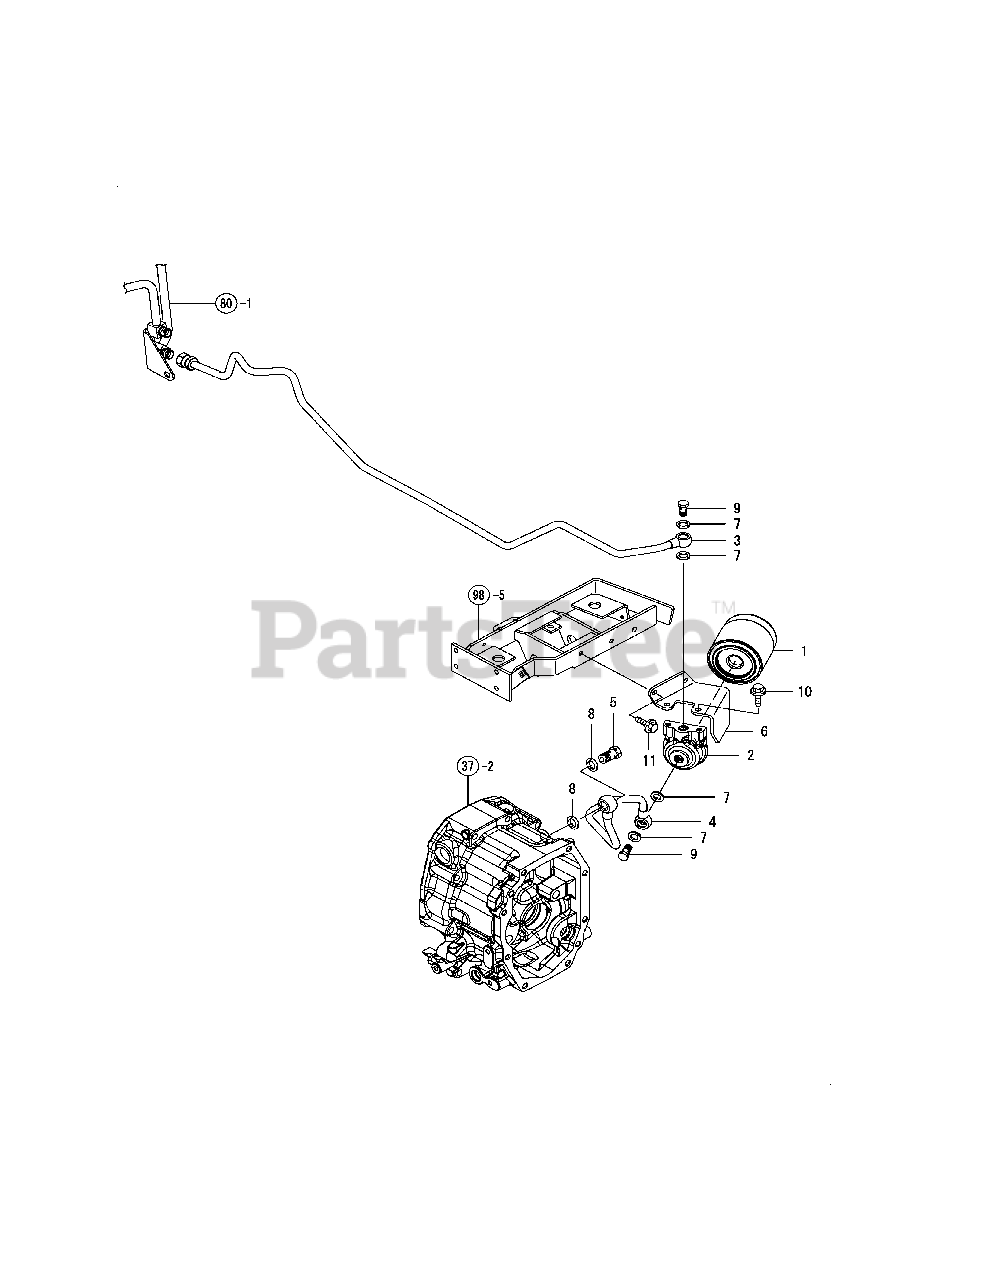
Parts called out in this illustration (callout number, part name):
3	LINE ASSY, FILTER
4	LINE ASSY, FILTER-HST - S/N F000155 & BELOW
4	LINE ASSY, FILTER-HST - S/N F000156 & ABOVE
5	CONNECTOR ASSY
6	BRACKET, FILTER
10	BOLT M 8X 16 PLATED
11	BOLT M 8X 12 PLATED
